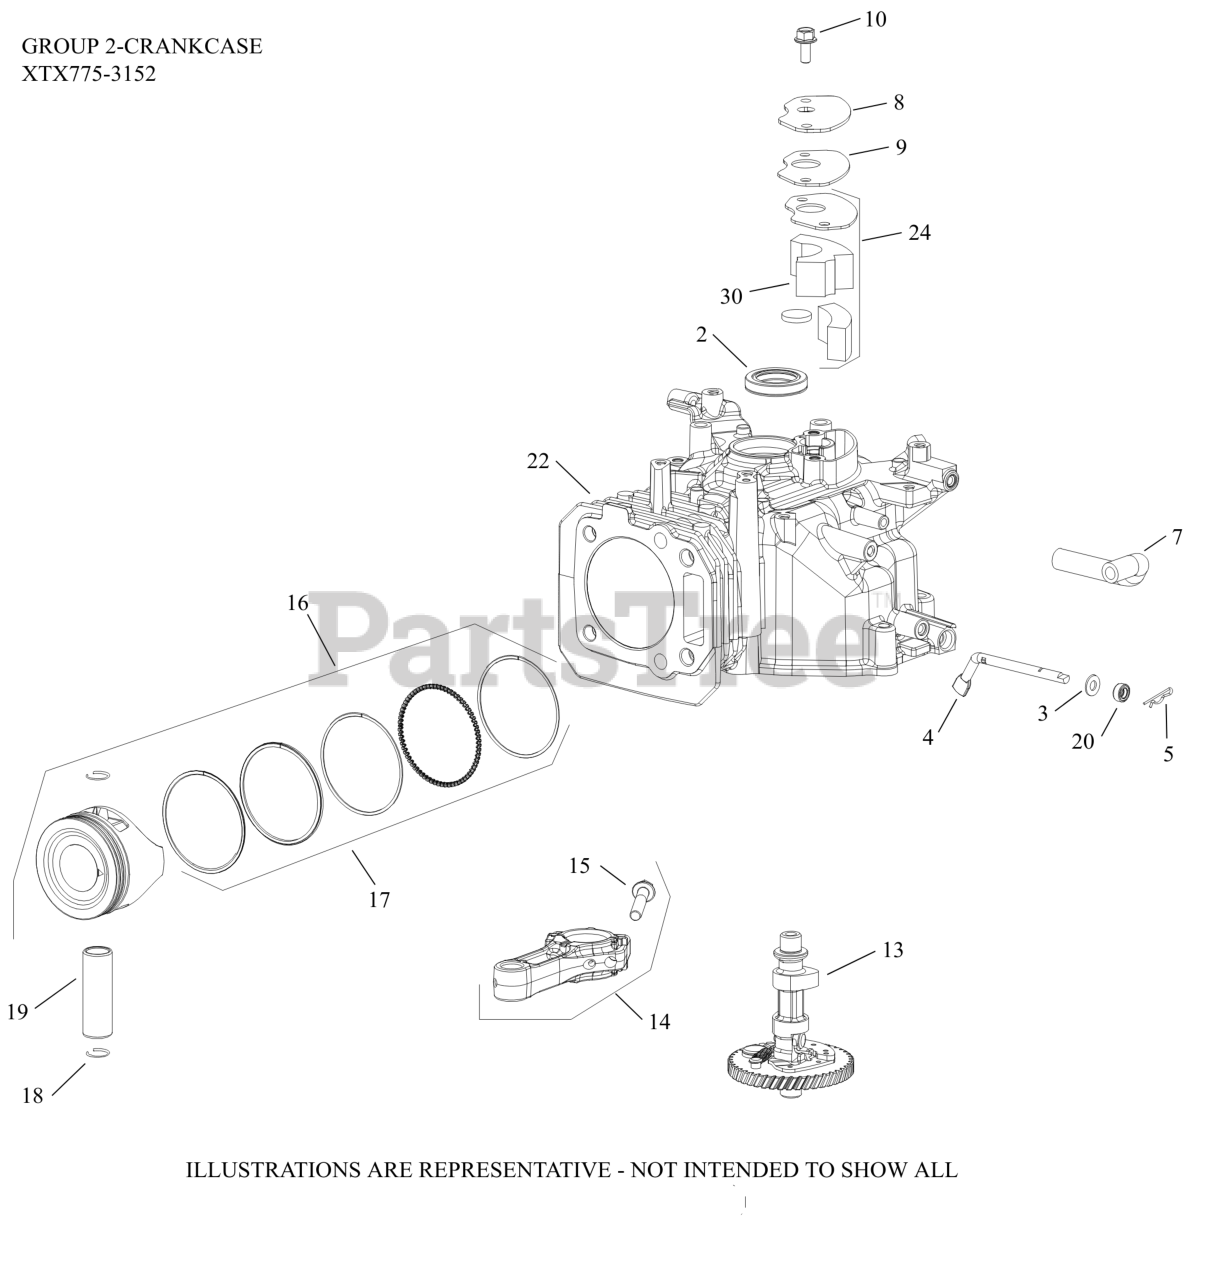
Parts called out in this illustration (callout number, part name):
2	SEAL, CCASE/FLYWHEEL
3	WASHER, FLAT (DIA 13mm O.D.)
4	SHAFT, GOVERNOR CROSS
5	CLIP, GOVERNOR SHAFT
7	HOSE, BREATHER
8	COVER, BREATHER
9	GASKET, BREATHER COVER
10	SCREW, HEX FLANGE (M6)-USE 25 086 433-S
13	CAMSHAFT ASSEMBLY
14	CONNECTING ROD
15	SCREW, HEX FLANGE (M7)
16	KIT, PISTON
18	RETAINER, PISTON PIN
19	PIN, PISTON
20	SEAL, OIL
22	CRANKCASE
24	KIT, BREATHER FILTER
30	FILTER, BREATHER MEDIA-USE 14 050 31-S
